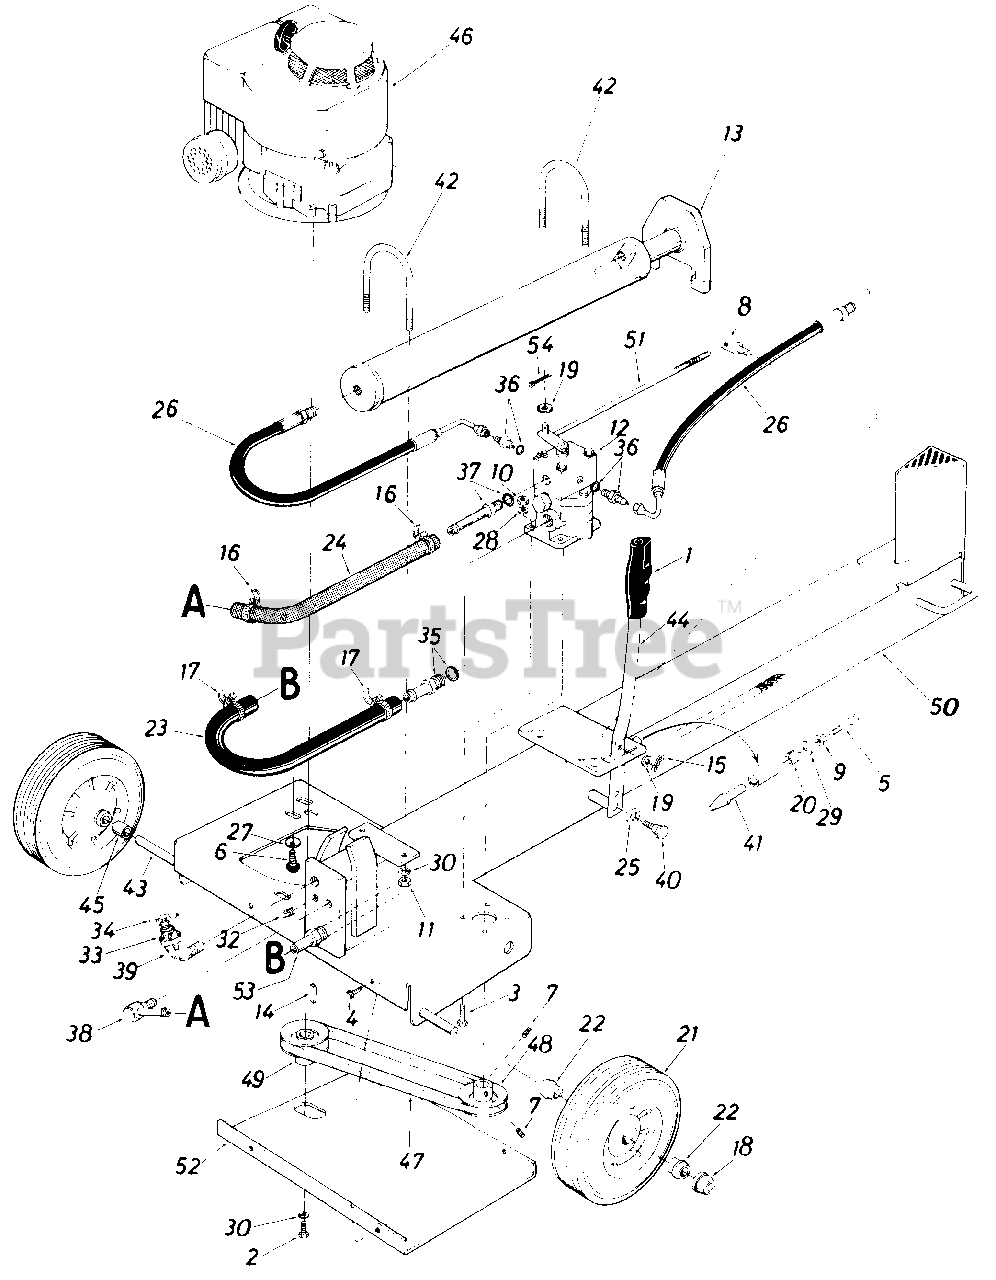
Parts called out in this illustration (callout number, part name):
1	Grip
2	Hex Bolt 3/8-24 x 1.00" Lg.
3	Hex Bolt 5/16-18 x 1.00" Lg.
4	Hex Wash. Hd. TT Tap Scr 1/4-20 x .50" Lg.
5	Hex Bolt 5/16-24 x 1.5 Lg.
6	Hex Wash. Hd. TT Tap Scr. 3/8 16 x .87" Lg.
7	Set Scr. 1/4-28 x .25" Cup
8	Adjustment Ferrule 5/16-18 Thd.
9	Hex Nut 5/16-24 Thd.
10	Hex Nut 5/16-18 Thd.
11	Hex Nut 3/8-16 Thd.
12	Valve in Head Pump Ass'y.
13	Cylinder Ass'y.
14	Sq. Key 3/16 x 1-1/2" Lg.
15	Hair Pin Cotter
16	Hose Clamp 3/4" I.D.
17	Hose Clamp 1.0" I.D.
18	Push Cap .625" Dia. Black
19	Fl.-Washer 5/16" I.D. x 5/8" O.D.
20	Compression Spring .64 I.D. x .81 Lg.
21	Wheel Ass'y. Comp. 10. x 2.75
22	Flange Bearing
23	Suction Hose 3/4" I.D. (Tank to Pump)
24	Return Hose 1/2" I.D. (Pump to Tank)
25	Wave Wash. .53" I.D. x .78" O.D.
26	High Pressure Hose (Forward 5 Return)
27	Bell.-Wash. .400" I.D. x .88" O.D.
28	L.-Wash. 5/16" I.D.
29	Fl.-Wash. .341" I.D. x .88" O.D.
30	L.-Wash. 3/8" I.D.
32	Plug 1/4 NPTF Sq. Hd.
33	Female Adapter 1/4 NPTF
34	Breather Valve 1/4 NPTF-M
35	Adapter 3/4 Tubing to 3/4-16 M-Boss
36	Adapter - or Boss to MJIC 9/16-18 to 7/16-20
37	Adapter 1/2 Tube 9/16-18 O.R. M-Boss
38	90° Elbow Adapter 1/2" Tube 1/2 NPTF
39	90° Elbow - 1/2 NPTF Nipple
40	Shld. Scr. .498 Dia. x .170" Lg.
41	Return Stroke Stop Plunger
42	Cylinder Support Rod
43	Axle Shaft 5/8" Dia. x 25.25" Lg.
44	Engagement Lever .88" O.D. x 17" Lg.
45	Spacer 5/8" I.D. x 7/8" O.D. x .90" Lg.
46	Engine 3-1/2 H.P.
47	(4L) Belt 1/2" V x 30" Lg.
48	1/2" V-Pulley 5/8" I.D. x 3-1/4" O.D.
49	1/2" V-Pulley 7/8" I.D. x 3-1/4" O.D.
50	Oil Tank & Frame Ass'y. Comp.
51	Engagement Rod 5/16-24 Thd.
52	Belt Cover
53	Strainer Tube Ass'y.
54	Cotter Pin 3/32" Dia. x .75" Lg.
